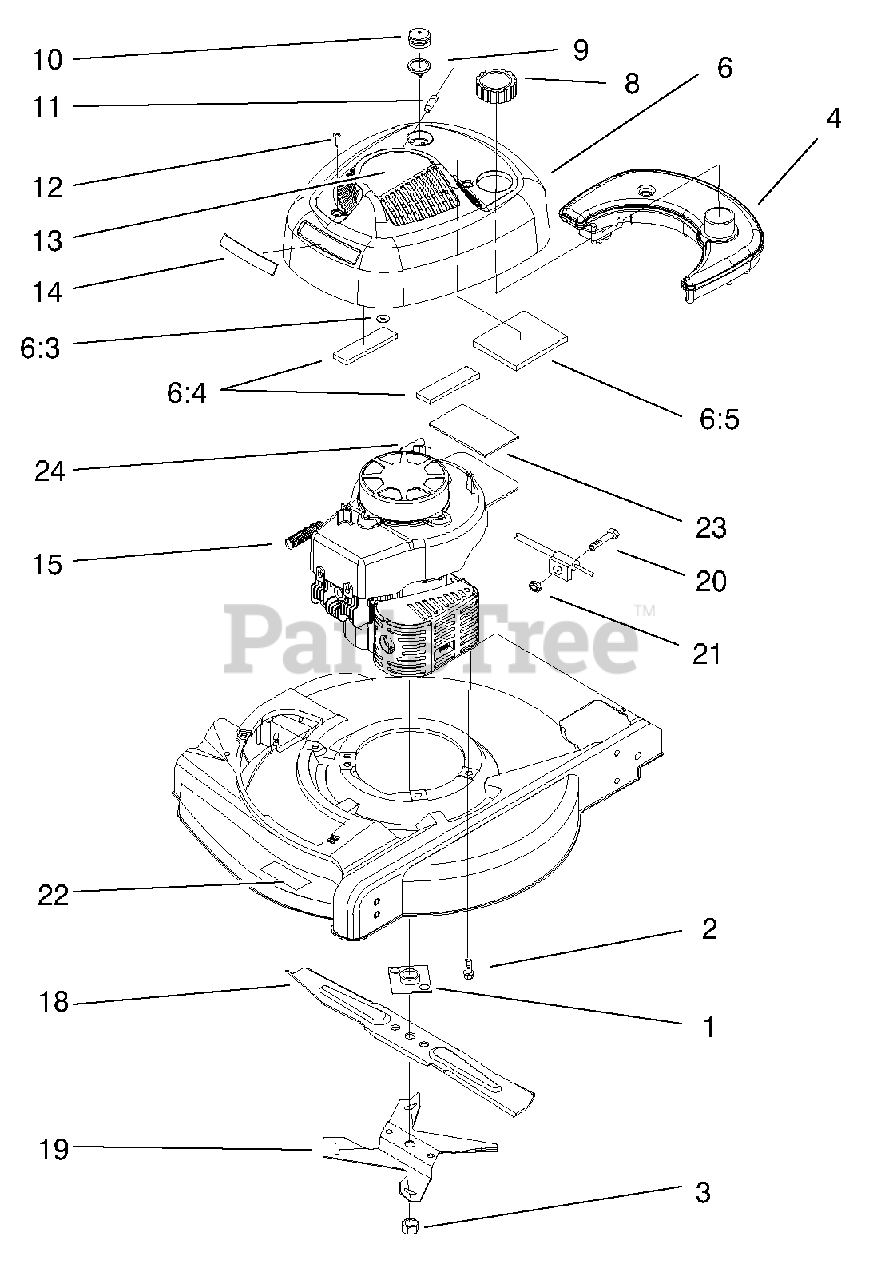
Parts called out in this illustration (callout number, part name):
1	Plate & Collar ASM
2	Screw-HH
3	Nut-Blade
6	Shroud & Recoil Cover ASM
6:3	Push Nut
6:4	Strip-Foam
6:5	Strip-Foam
8	Cap ASM-Fuel & Oil
9	Body-Primer
10	Bulb-Primer
11	Rope-Stop
12	Screw-Pan Sems
13	Decal-Recoil
14	Applique-Shroud
15	Spring-Compression
18	Blade
19	Fan-Mulching
21	Nut-Hex
22	Decal-Deck
23	Pad-Foam
24	Fuel Line
